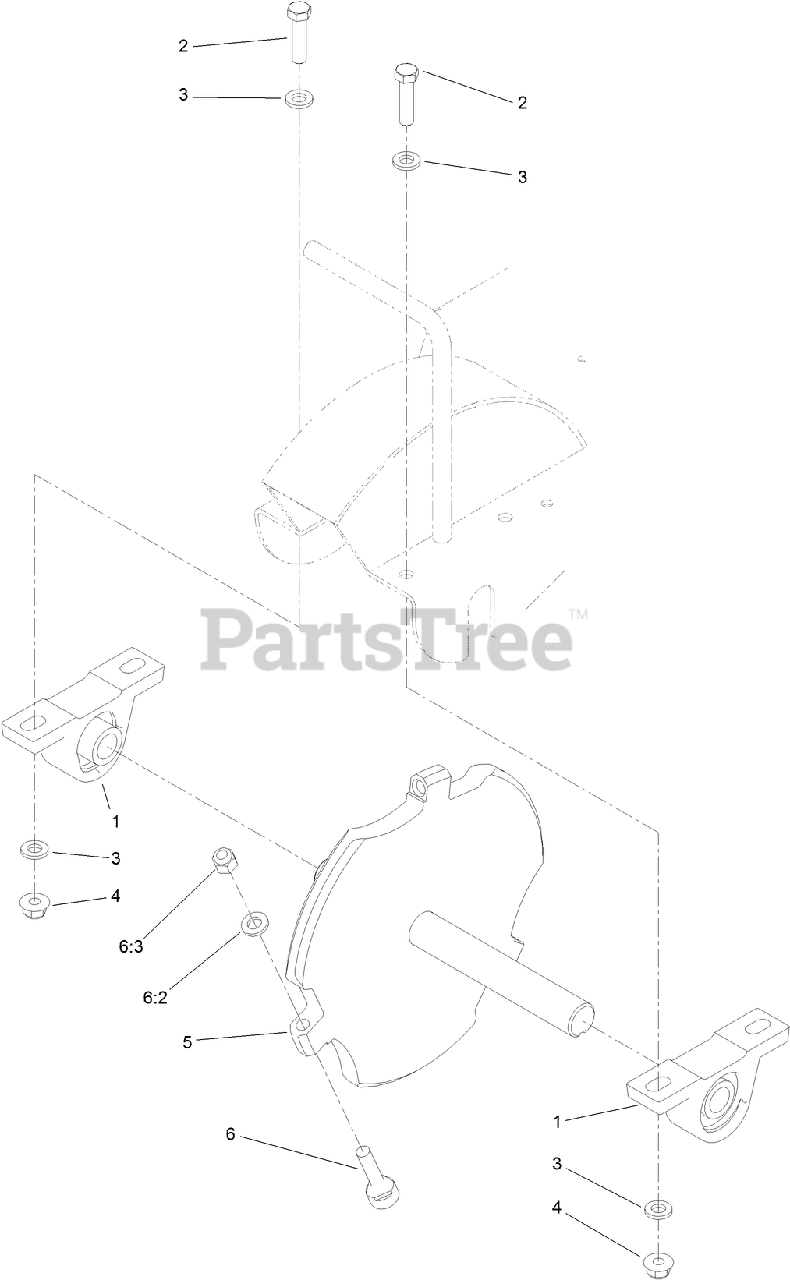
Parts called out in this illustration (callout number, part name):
1	BEARING
2	SCREW-HH
3	WASHER-HARDENED
4	NUT-HF, NI
5	WHEEL-CUTTER
6	GRINDER TOOTH ASM
6:2	WASHER-HARDENED
6:3	NUT-LOCK, NI
